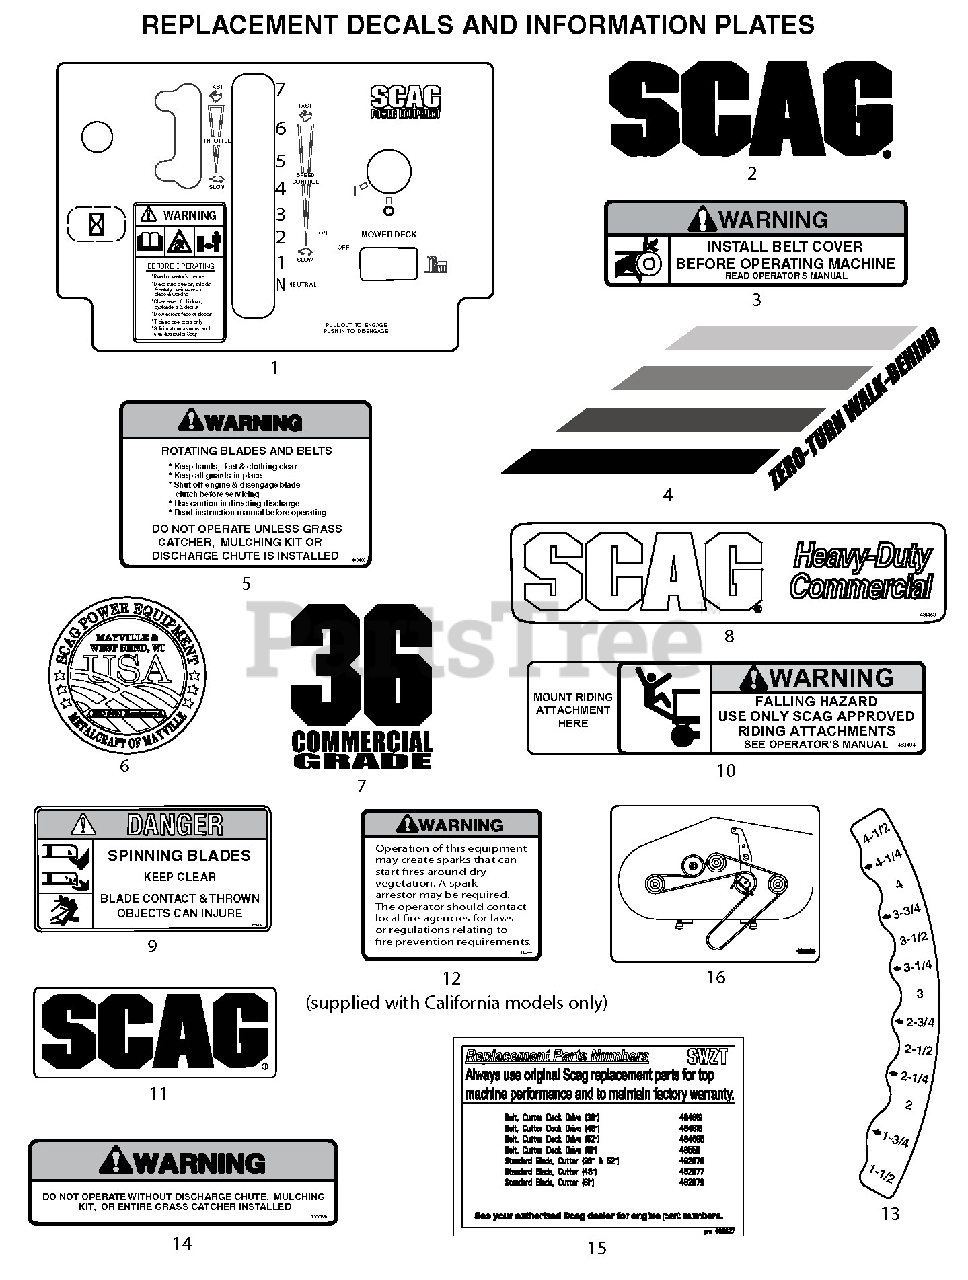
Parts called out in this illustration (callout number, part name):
1	Decal, Instrument Panel (Manual Start)
1	Decal, Instrument Panel (Electric Start Only)
2	Decal, Scag Logo
3	Decal, Belt Cover
4	Decal, Handle - LH
4	Decal, Handle - RH
5	Decal, Warning-Rotating Blades
6	Decal, Metalcraft - USA
7	Decal, 36 Commercial
7	Decal, 48 Commercial
7	Decal, 52 Commercial
8	Decal, Scag Heavy Duty
9	Decal, Spinning Blades
10	Decal, Sulky Attachment
11	Decal, Scag Logo
12	Decal, Warning Spark Arrestor
13	Decal, Height of Cut
14	Decal, Warning
15	Decal, SWZT Replacement Parts
16	Decal, Belt Routing
